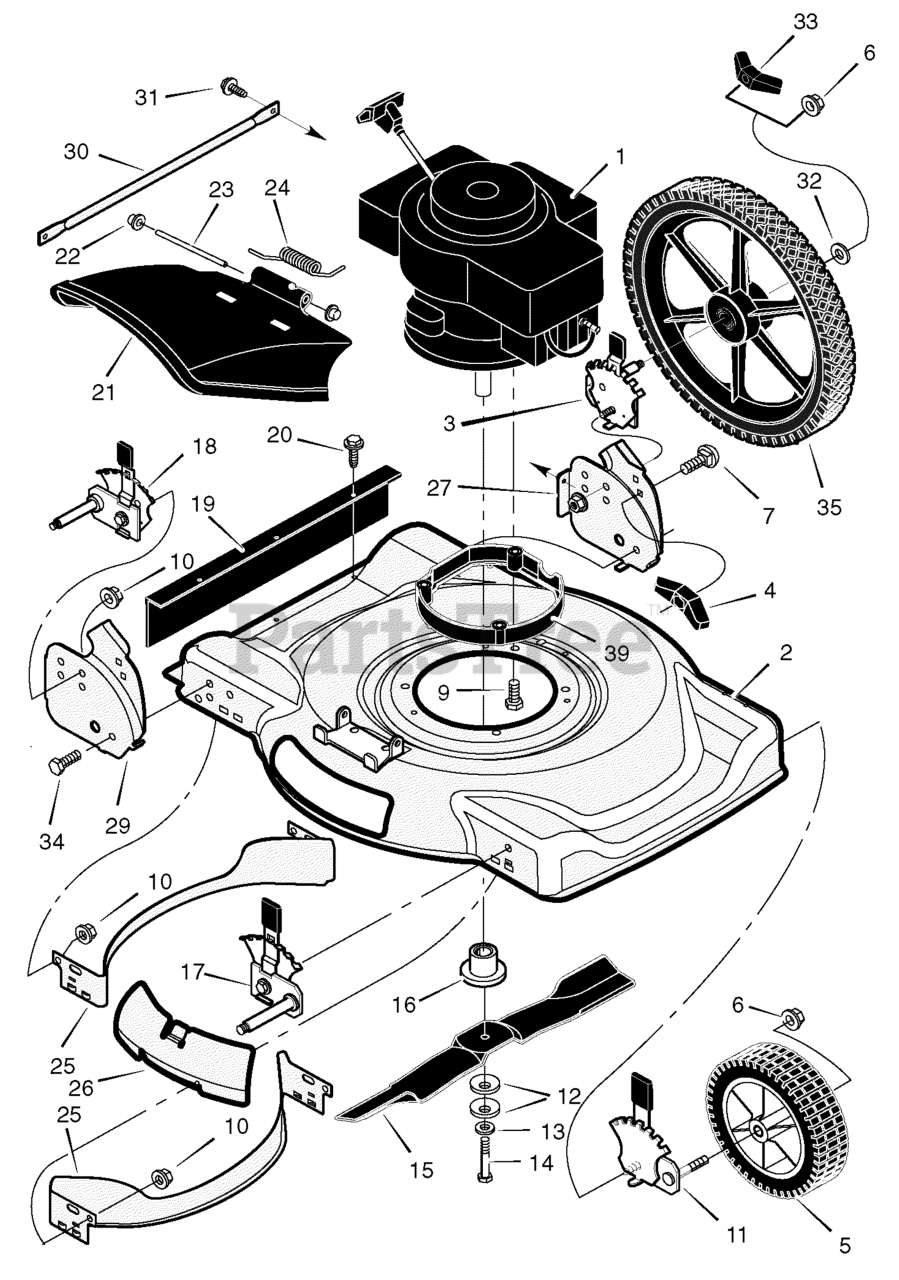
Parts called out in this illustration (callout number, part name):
1	Engine **
2	Housing
3	Height Adjuster, Left Rear
5	Wheel and Tire, Front
6	Locknut, Flange
7	Bolt, Carriage
9	Bolt, Engine
10	Nut
11	Height Adjuster, Left Front
12	Washer, Belleville
13	Washer
14	Bolt, Hex
15	Blade, Side Discharge
15	Blade, Mulcher
16	Adapter, Blade
17	Height Adjuster, Right Front
18	Height Adjuster, Right Rear
19	Guard, Rear
21	Deflector, Chute
22	Push-On Cap
23	Pin, Pivot
24	Spring
26	Plate, Mulcher
27	Bracket, Left Handle
29	Bracket, Right Handle
31	Screw
33	Knob, Axle
34	Bolt
35	Wheel and Tire, Rear
39	Base, Engine
